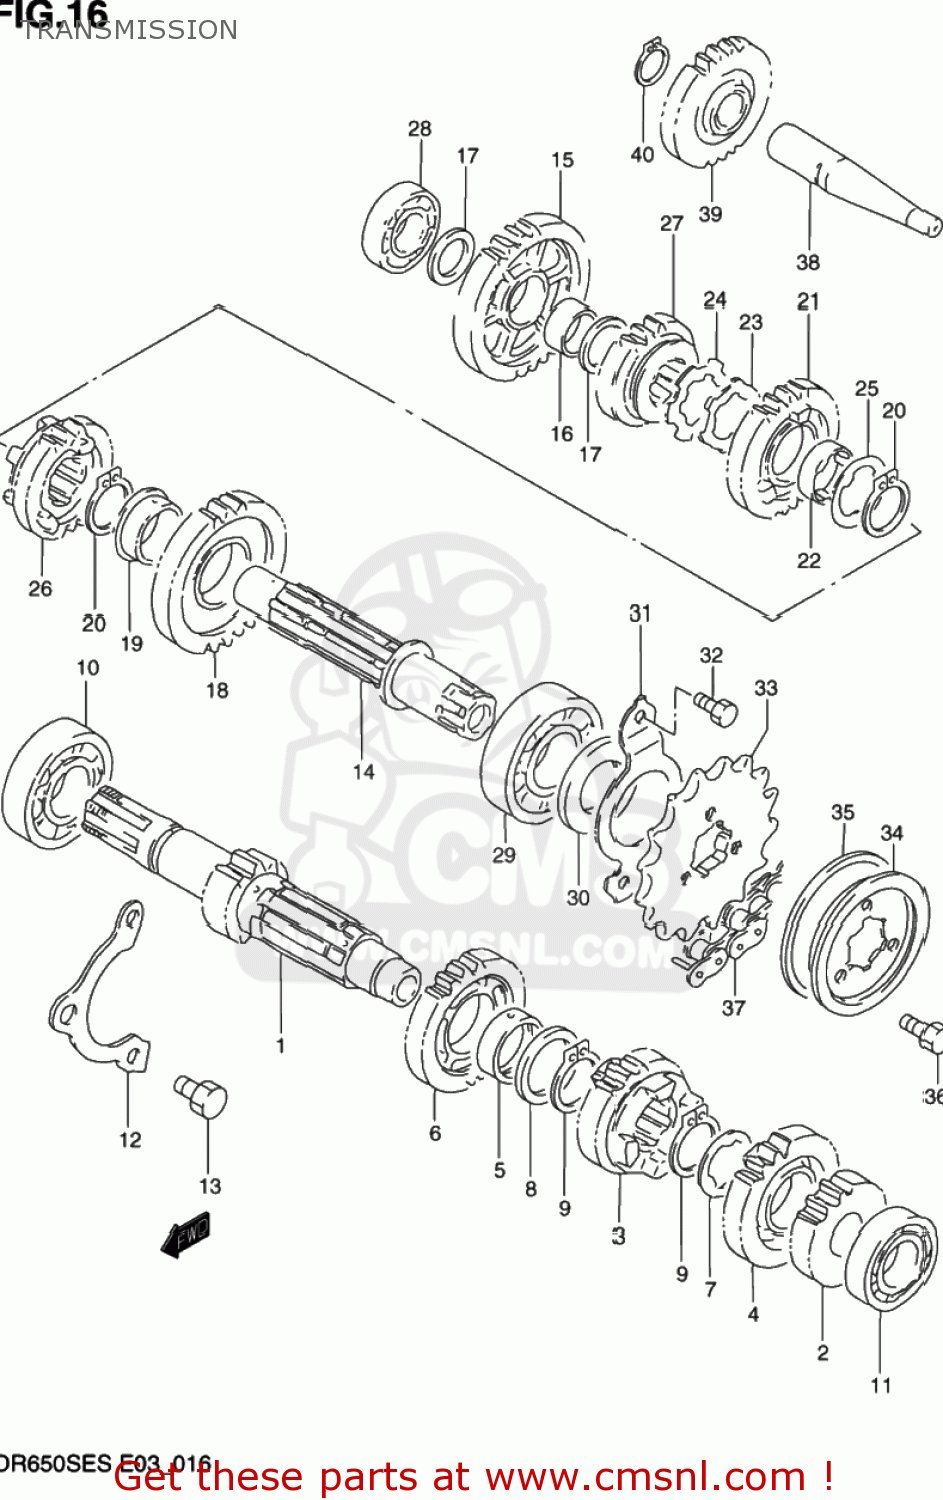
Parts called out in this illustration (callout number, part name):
1	SHAFT,COUNTER
2	GEAR,SECOND DRIVE
3	GEAR,3RD DRIVE
4	GEAR,FOURTH DRIVE
5	BUSHING 25X29X10
6	GEAR,5TH DRIVE
7	WASHER,LOCK
8	WASHER
9	RING,SNAP
10	BEARING
11	BEARING
12	RETAINER,CNTR SHAFT BEARING
13	BOLT
14	SHAFT,DRIVE
15	GEAR,1ST DRIVEN
16	BUSH(20X24X13)
17	WASHER
18	GEAR,2ND DRIVEN
19	BUSH
20	RING,SNAP
21	GEAR,3RD DRIVEN
22	BUSHING
23	WASHER
24	WASHER,LOCK
25	WASHER,LOCK
26	GEAR,FOURTH DRIVEN
27	GEAR,FIFTH DRIVEN
28	BEARING(20X42X12)
29	BEARING(25X62X17)
30	SEAL,OIL(25X45X5)
31	RETAINER,DRIVE SHAFT OIL SEAL
32	BOLT
33	SPROCKET,ENGINE(NT:16)
34	PLATE,ENGINE SPROCKET
35	DAMPER,ENGIN SPROCKET
36	BOLT(6X13)
37	CHAIN(DID520V,114L)
38	SHAFT,KICK STARTER IDLE
39	GEAR,KICK STARTER IDLE
40	CIRCLIP
